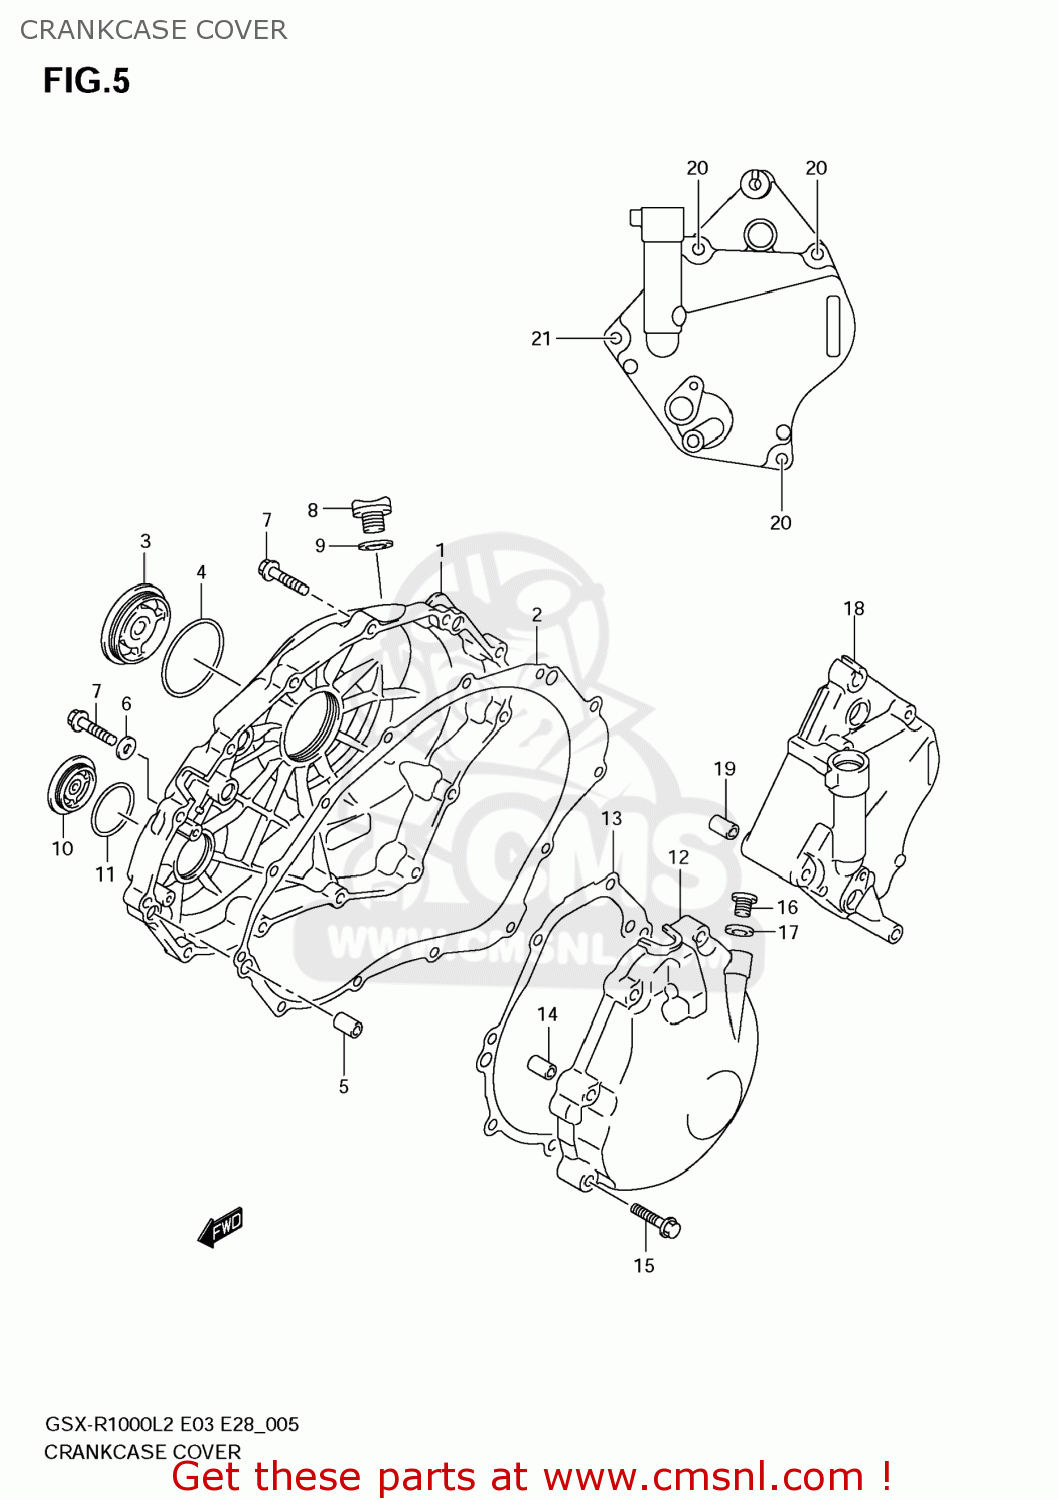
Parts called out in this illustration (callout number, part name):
1	COVER,CLUTCH
2	GASKET,CLUTCH COVER (NAS)
3	CAP,CLUTCH RELEASE ADJUST
4	O RING
5	PIN
6	GASKET(5.8X13X1.2) (NAS)
7	BOLT(6X30)
8	PLUG,ENGINE OIL FILLER
9	O RING(D:3.1,ID:16.8)
10	PLUG
11	O RING(D:3.1,ID:32.7)
12	COVER,GENERATOR
13	GASKET,GENERATOR COVER (NAS)
14	PIN
15	BOLT(6X30)
16	PLUG(10X10)
17	GASKET(10X14X3.6) (NAS)
18	COVER,ENGINE SPROCKET
19	PIN
20	BOLT(6X45)
21	BOLT(6X65)
